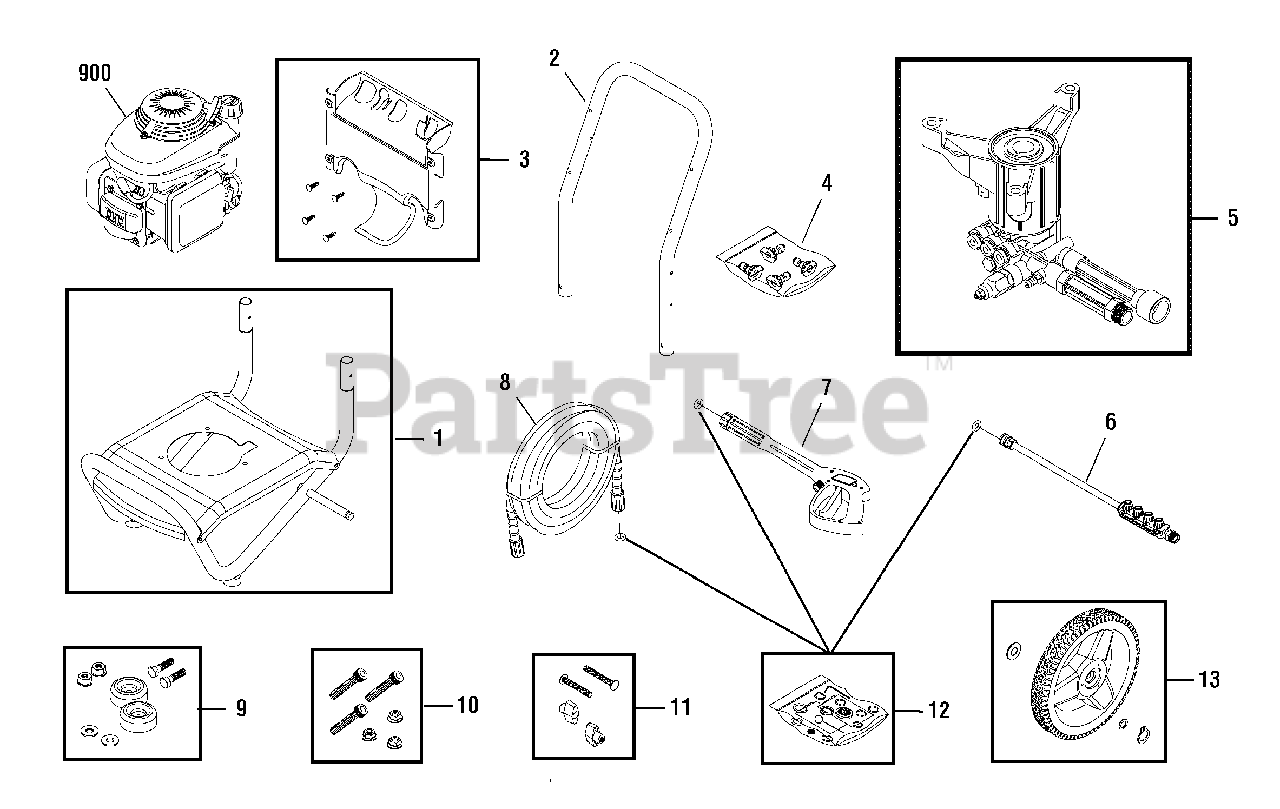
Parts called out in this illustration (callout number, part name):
4	KIT, QC Nozzles
5	PUMP
6	EXTENSION, QC
7	GUN
8	HOSE
9	MOUNT, Vibration
10	KIT, Hardware, Pump Mounting
11	KIT, Hardware, Handle
12	KIT, O-Ring
900	* ENGINE
